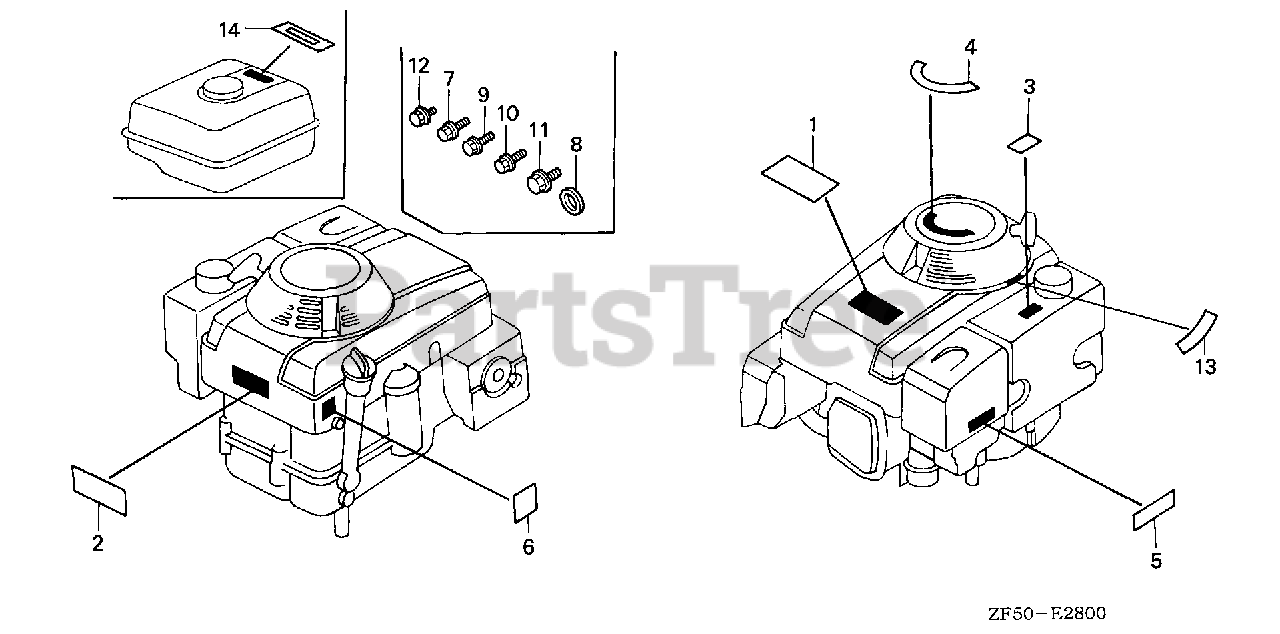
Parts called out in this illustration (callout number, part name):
1	EMBLEM, TOP COVER (ENGLISH)
2	LABEL, EMBLEM (H)
3	LABEL, FUEL CAUTION (ENGLISH)
4	MARK, EASY START (ENGLISH)
5	MARK, AIR CLEANER CAUTION
6	MARK, OIL CAUTION
